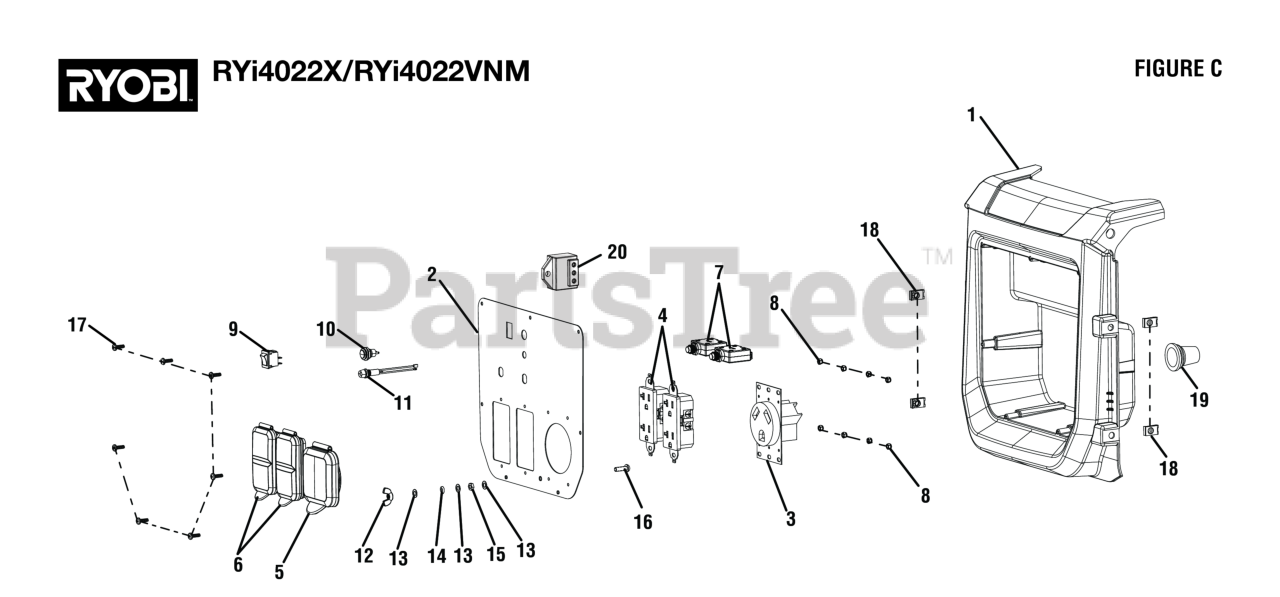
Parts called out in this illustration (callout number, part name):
1	Electrical Panel Housing
2	Control Panel
3	Twist Lock Receptacle (120 Volt, 30 Amp)
4	120 Volt Duplex Receptacle (BM903611)
5	Outlet Cover
6	120 Volt Receptacle Rain Cover
7	Circuit Breaker (20 Amp)
8	Lock Nut (M4)
9	Auto Idle Switch
10	Reset Button
11	Indicator (Red LED 3.3V-4mA)
12	Wing Nut (M5)
13	Flat Washer (OD10 x ID5.3 x 0.5t)
14	Lock Washer (OD9 x ID5 x 1.3t)
15	Hex Nut (M5)
16	Screw (M5 x 16 mm, Phillips Pan Hd.)
17	Screw (M4.2 x 12mm, Phillips Button Hd.)
18	U-Clip (M6)
19	Wiring Rubber Boot
20	Ignition Module
